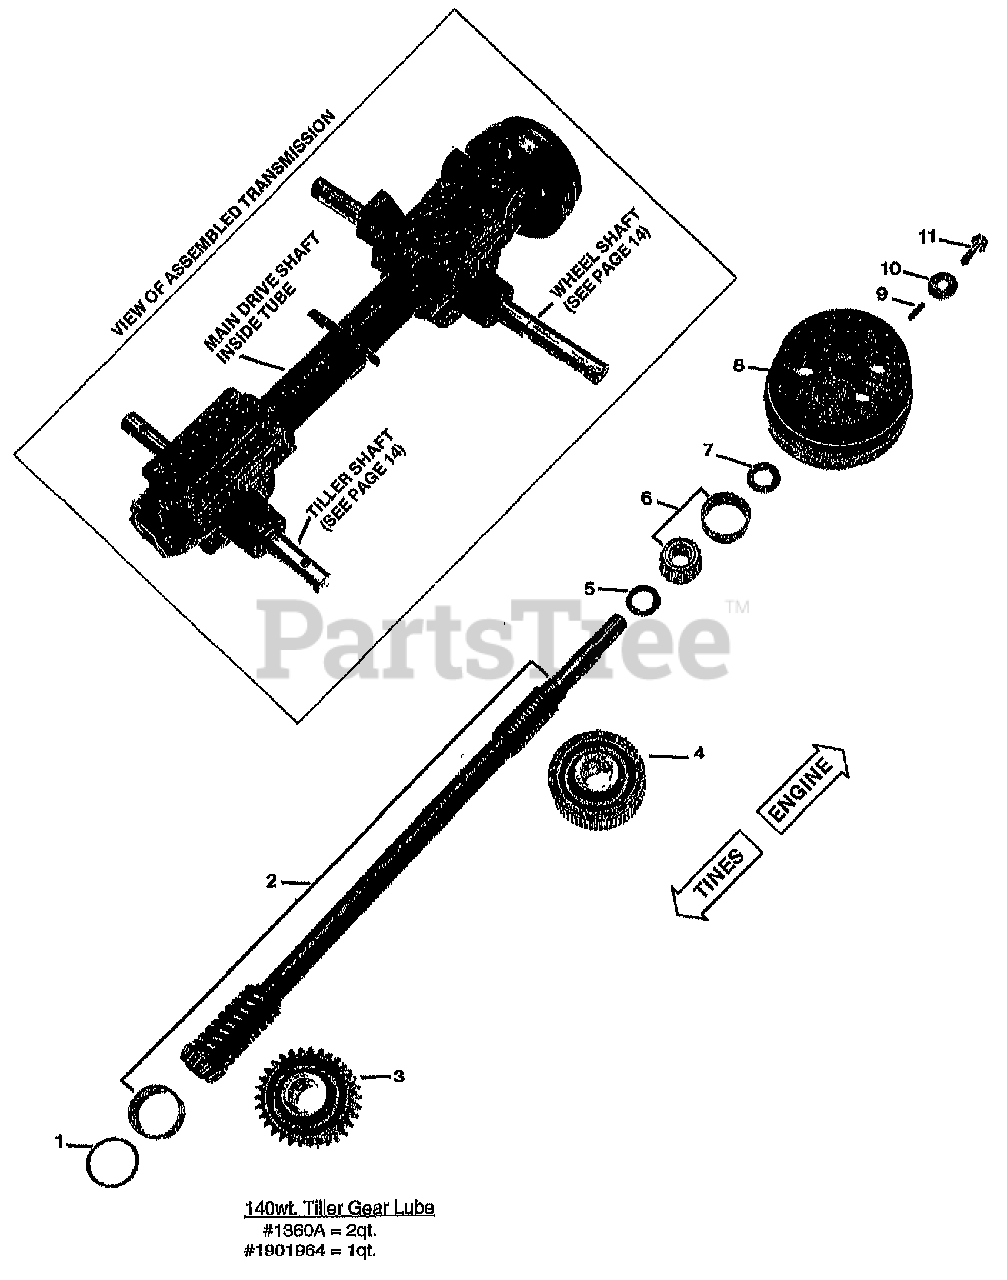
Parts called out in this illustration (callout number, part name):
1	SHIM-1.75X1.5X.01
1	SHIM-1.75X1.5X.03
1	SHIM-1.75X1.5X.005
2	KIT-DRIVESHAFT JR
3	GEAR-WORM BRONZE MACH (Tiller Drive)
4	GEAR-WORM 61 TEETH MACH (Wheel Drive)
5	WASHER-#1.25X.75X.06
6	KIT-BRG CONE & RACE-DRIVESHAFT
7	WASHER-SHLDR HARDENED 11/16""I.D. x 11/4" O. D. (Thrust external, hardened)
8	PULLEY-TRANS MACH (Transmission drive, 2 belt grooves
9	KEY-.188 SQ X .75 (Transmission pulley to drive shaft)
10	WASHER-.827X.331X.098
11	SCR-FLHH 5/16-24 X .75 ZP(Pulley to drive shaft)
